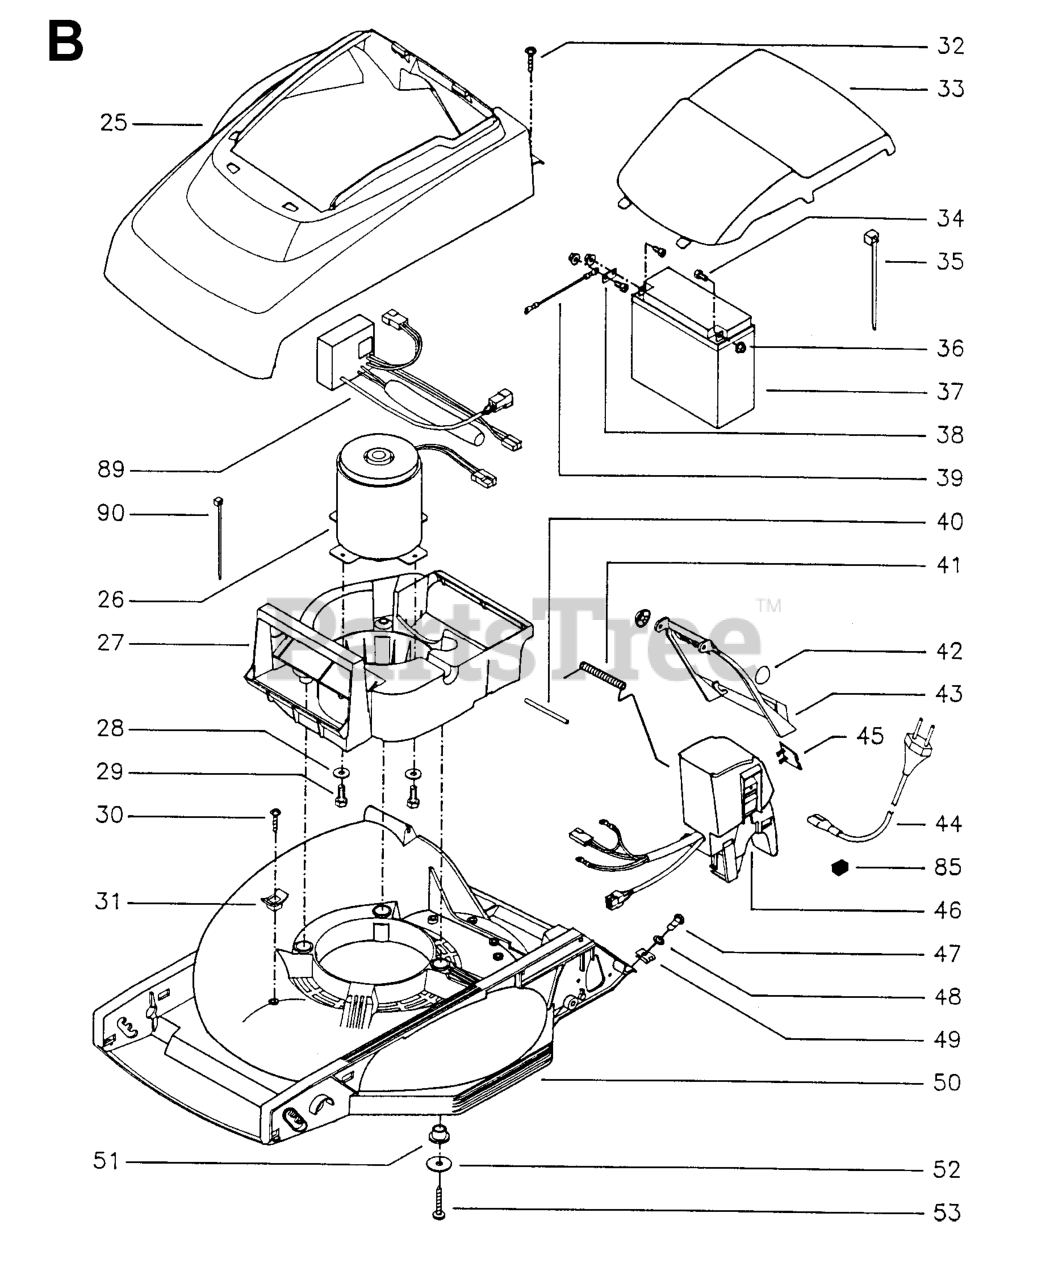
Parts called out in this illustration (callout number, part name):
32	SCREW
40	PIN
49	LOCK PLATE
